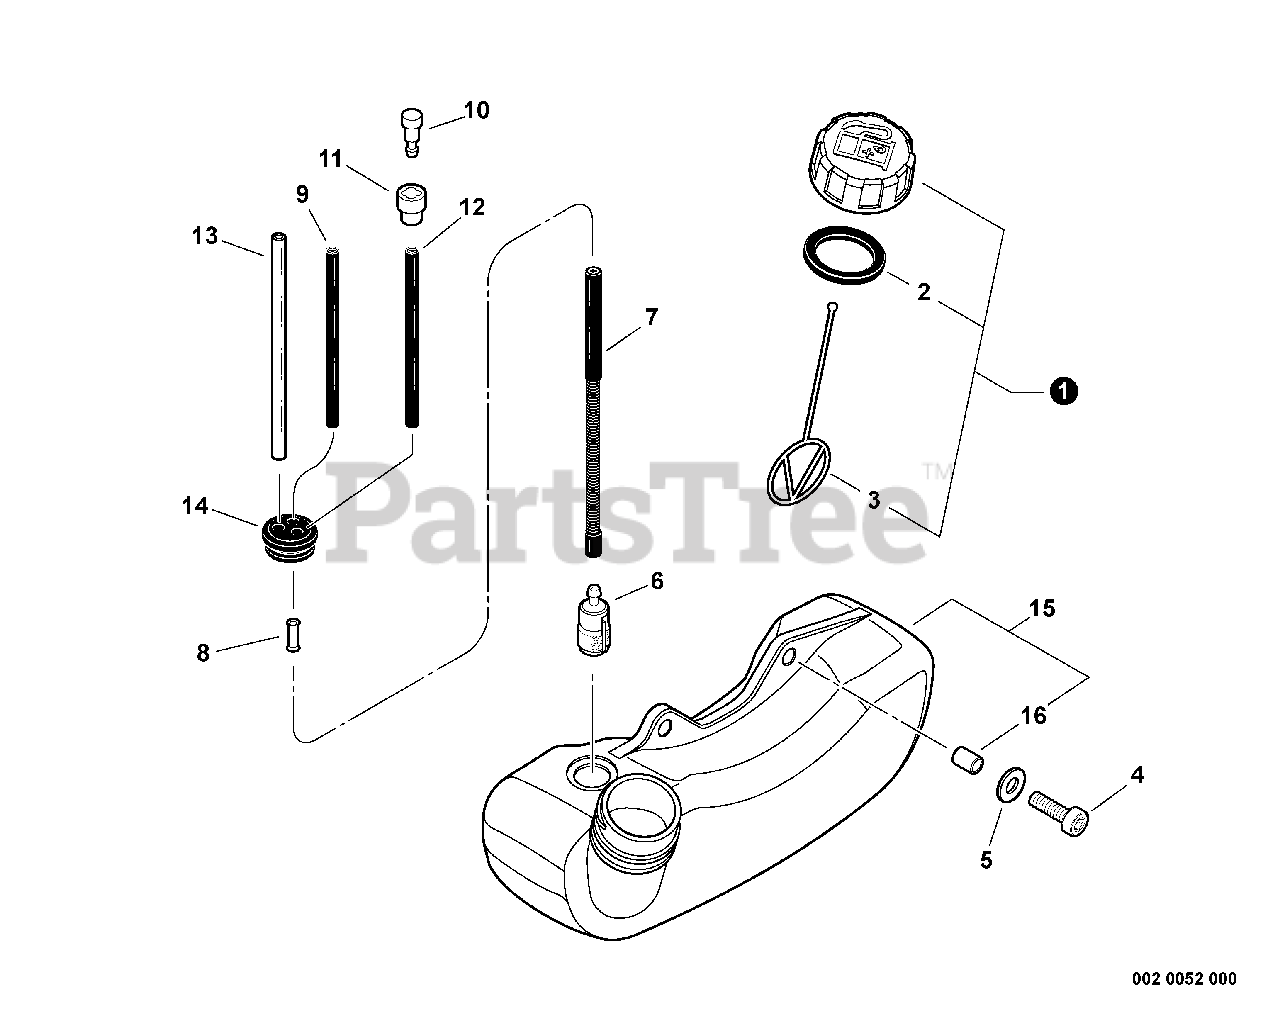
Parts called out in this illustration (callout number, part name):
1	CAP ASSY - ORANGE
2	GASKET, CAP
3	CONNECTOR, CAP
4	SCREW - 5X16
5	WASHER - 5
6	FILTER, FUEL
7	PIPE, FUEL - CORRUGATED
8	CONNECTOR, PIPE
9	PIPE - 3X5X90 -- BLACK
10	VENT, FUEL TANK
11	COVER, VENT
12	PIPE - 3X5X70 -- BLACK
13	PIPE - 3X6X90 -- CLEAR
14	GROMMET
15	FUEL TANK ASSY
